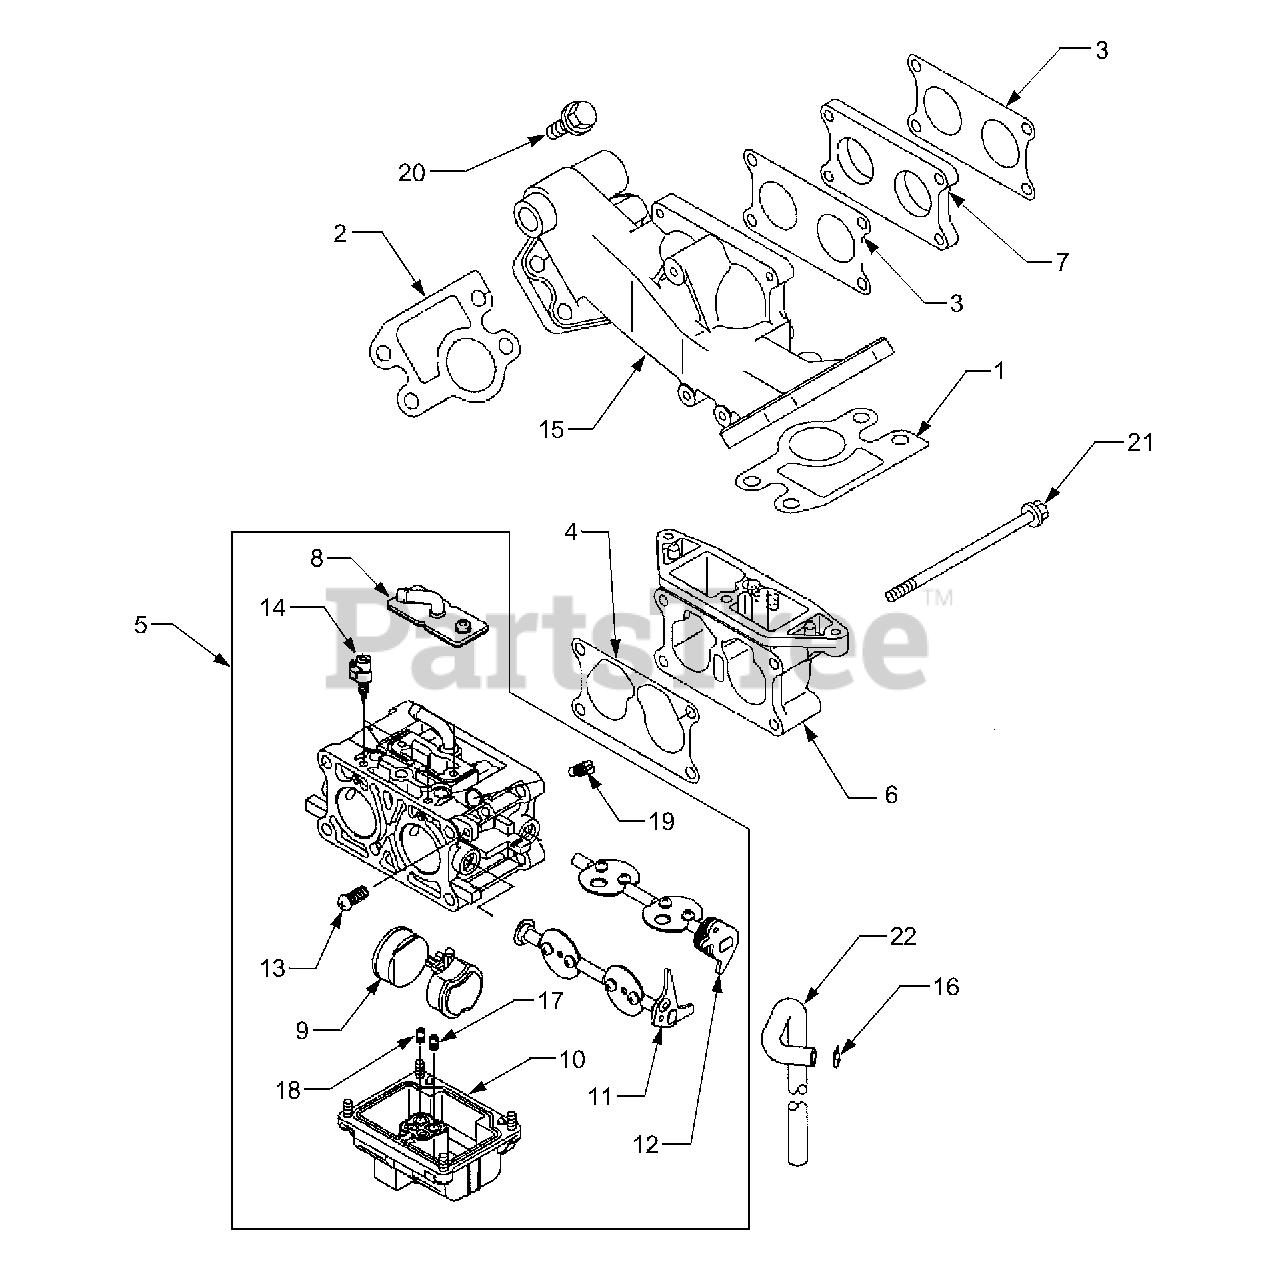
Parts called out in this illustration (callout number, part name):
1	Gasket, Intake Manifold
2	Gasket, Intake Manifold
3	Gasket, Intake Pipe
5	Carburetor Assembly
8	Cover Assembly
9	Float Assembly
10	Chamber, Float
11	Valve Assembly, Throttle
12	Valve Assembly, Choke
13	Screw Assembly
14	Screw Assembly
15	Manifold, Intake
17	Jet, Main, #110
18	Jet, Main, #111.3
19	Jet, Pilot, #45
20	Bolt, Flanged
21	Bolt, Flanged
